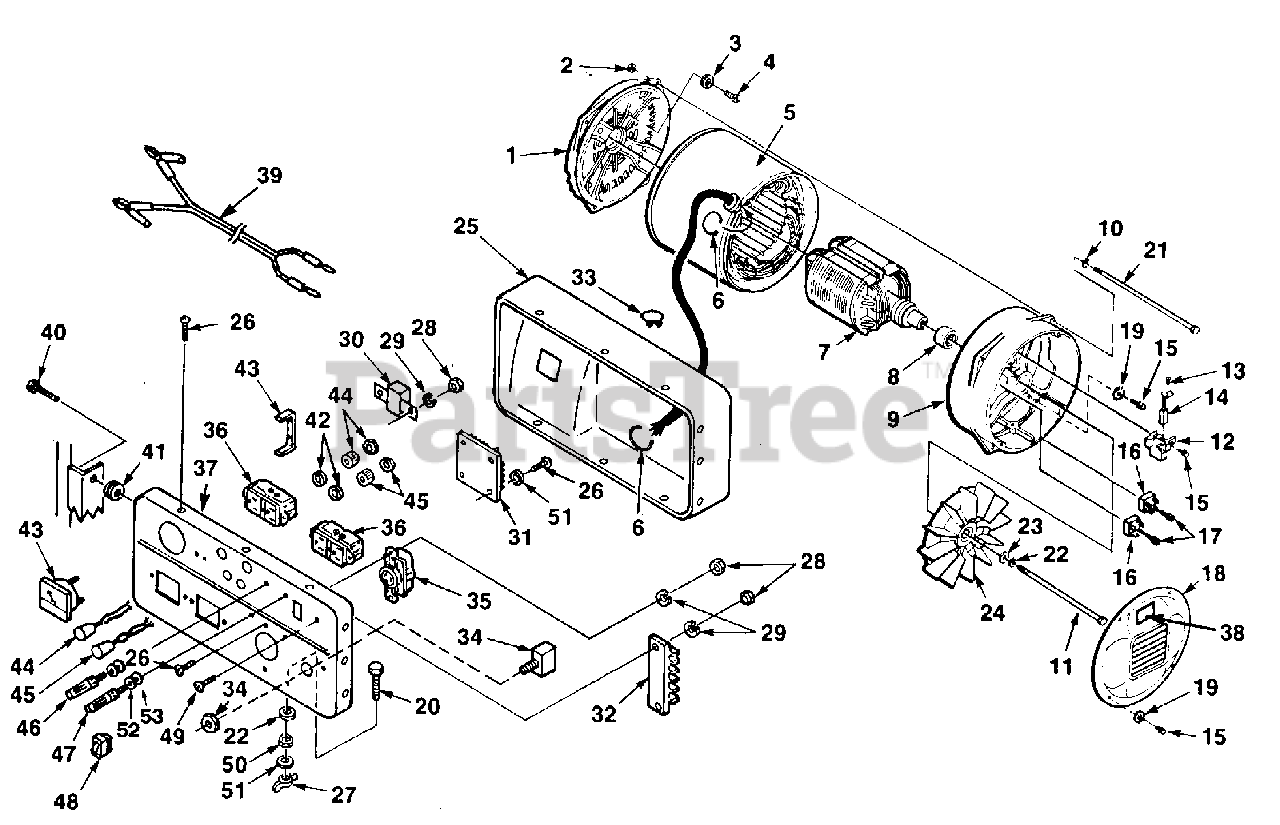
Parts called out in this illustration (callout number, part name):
1	END BELL-Generator
2	NUT-Hex (1/4-20")
3	WASHER-Lock Int./Ext.
4	SCREW-Hex Hd. (3/8-16 X 7/8")
5	STATOR & SHELL
6	TIE CABLE
8	BEARING
9	BRUSH HEAD
10	WASHER-Lock Int. (.035 thick)
11	BOLT-Rotor
12	BRUSH HOLDER
13	SCREW-Mach. (8-32 X 3/8")
15	SCREW-Thd. Form. (8-32)
16	RECTIFIER
17	SCREW-Thd. Form. (8-32 X 3/4")
18	COVER-Brush Head
19	WASHER-Lock Int. (#8)
20	SCREW-Hex Cap (5/16-18 X 1")
21	BOLT-Stator
22	WASHER-Lock (5/16")
23	WASHER-Flat (5/16")
25	PANEL COVER (Inc. #27)
26	SCREW-Pan Hd. (8-32 X 3/8")
27	NUT-Wing (5/16-18")
28	NUT (8-32)
29	WASHER-Lock (#8)
30	BREAKER-Circuit (D.C.)
31	VOLTAGE REGULATOR
32	BLOCK TERMINAL
33	CLAMP-Cable
34	BREAKER-Circuit (A.C.) (includes Nut)
35	RECEPTACLE-Locking (L14-20R)
36	RECEPTACLE- Duplex (GFCI) (5-15R)
37	PANEL-Control
38	DECAL-Warning
39	LEAD-D.C.
40	SCREW-Pan Hd. (1/4-20 X 3/4)
41	GROMMET-Isolator
42	WASHER-Flat (#10)
43	VOLTMETER
44	PILOT LIGHT (Red) (includes Nut & Washer)
45	PILOT LIGHT (Green) (includes Nut & Washer)
46	BANANA JACK (Black)
47	BANANA JACK (Red)
48	SWITCH-Rocker
49	SCREW-Pan Hd. (#8-32 X 5/8")
50	NUT-Hex (5/16-18")
52	WASHER-Insulating
53	WASHER-Shoulder
